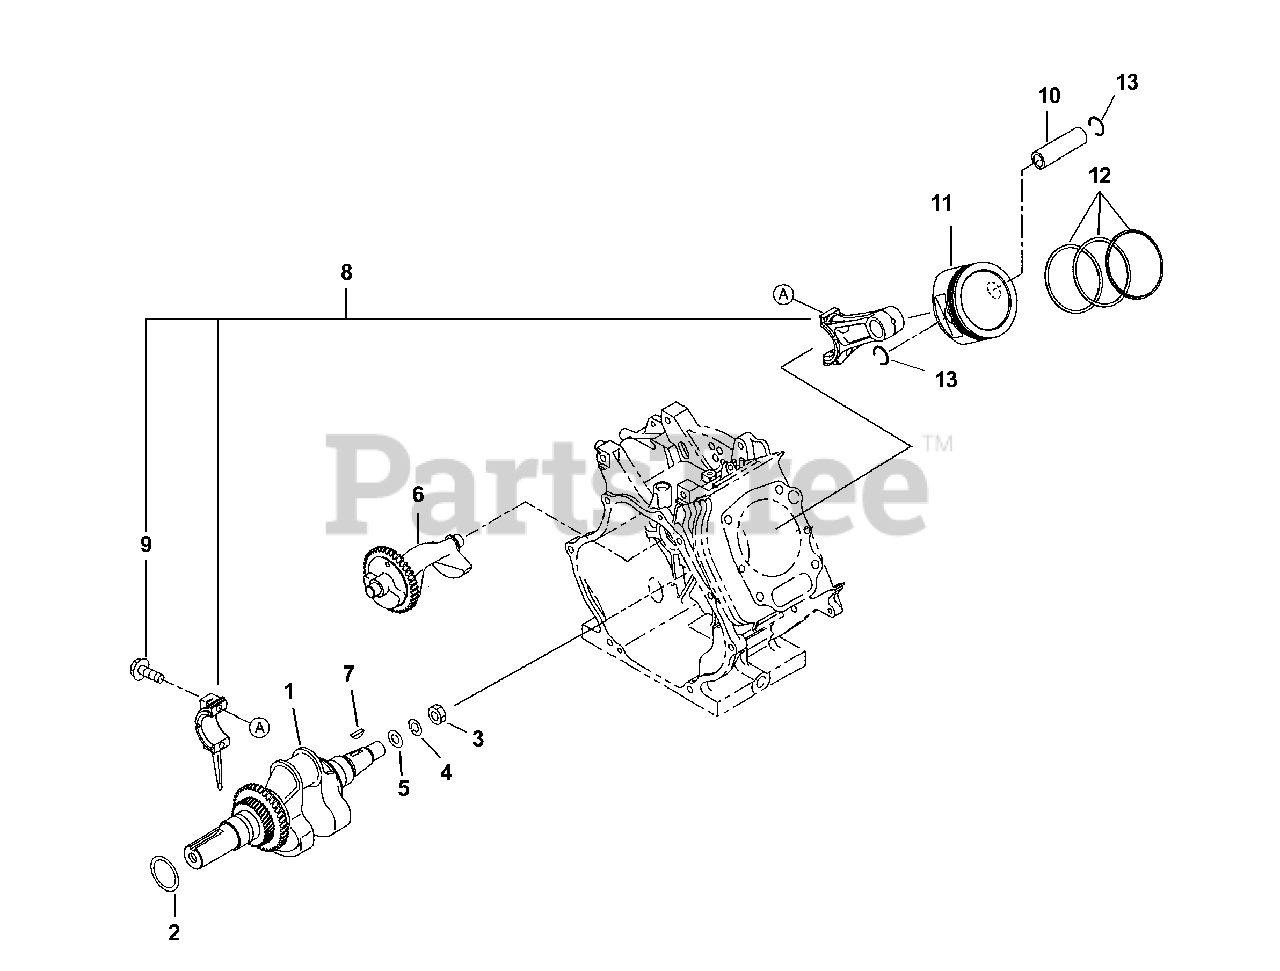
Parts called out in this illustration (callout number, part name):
1	Crankshaft cp
2	Spacer (.6)
3	Nut
4	Spring washer
6	Balancer shaft
7	Woodruff key
8	Connecting rod
9	Connecting rod bolt
10	Piston pin
12	Piston ring set
